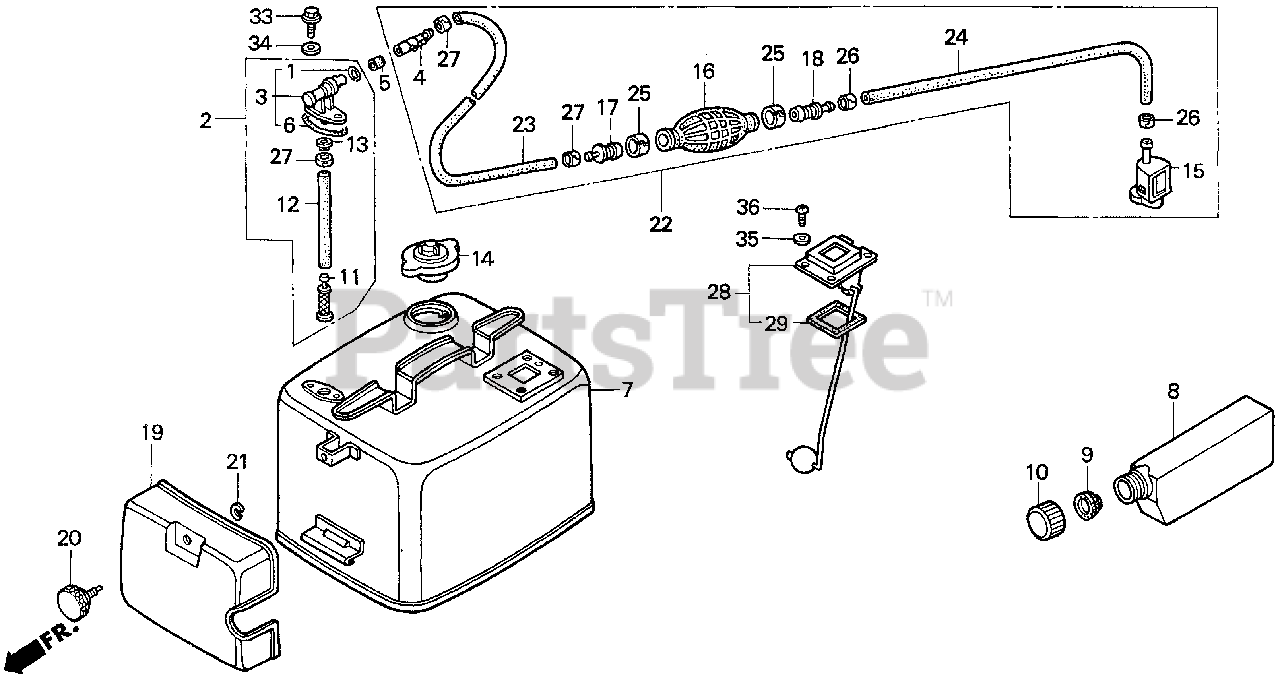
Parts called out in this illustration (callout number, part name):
2	JOINT A, FUEL
3	JOINT A, FUEL CONSENT
4	JOINT B, FUEL CONSENT
5	ABSORBER, FUEL
6	RING, PETCOCK SEAL
7	TANK, FUEL *R8* (BRIGHT RED)
9	CAP, SUB-TANK (INNER)
10	CAP, SUB-TANK
11	FILTER, FUEL
12	TUBE (INNER)
13	SEAL (INNER)
14	CAP, FUEL FILLER
15	CONNECTOR ASSY. A, FUEL
16	PRIMER BULB
17	VALVE, IN.
18	VALVE, OUTLET
20	LATCH, TOOL BOX
21	STOPPER, LATCH
22	TUBE ASSY., FUEL
23	TUBE, FUEL LONG
24	TUBE, FUEL SHORT
25	BAND, TUBE CLIP (20MM)
26	BAND, TUBE CLIP (12.5MM)
27	BAND, TUBE CLIP (11MM)
28	METER ASSY., FUEL
29	GASKET, FUEL METER
33	BOLT, FLANGE (6X16)
34	GASKET, FIBER (6MM)
35	GASKET, FIBER (5MM)
36	SCREW, PAN (5X10)
